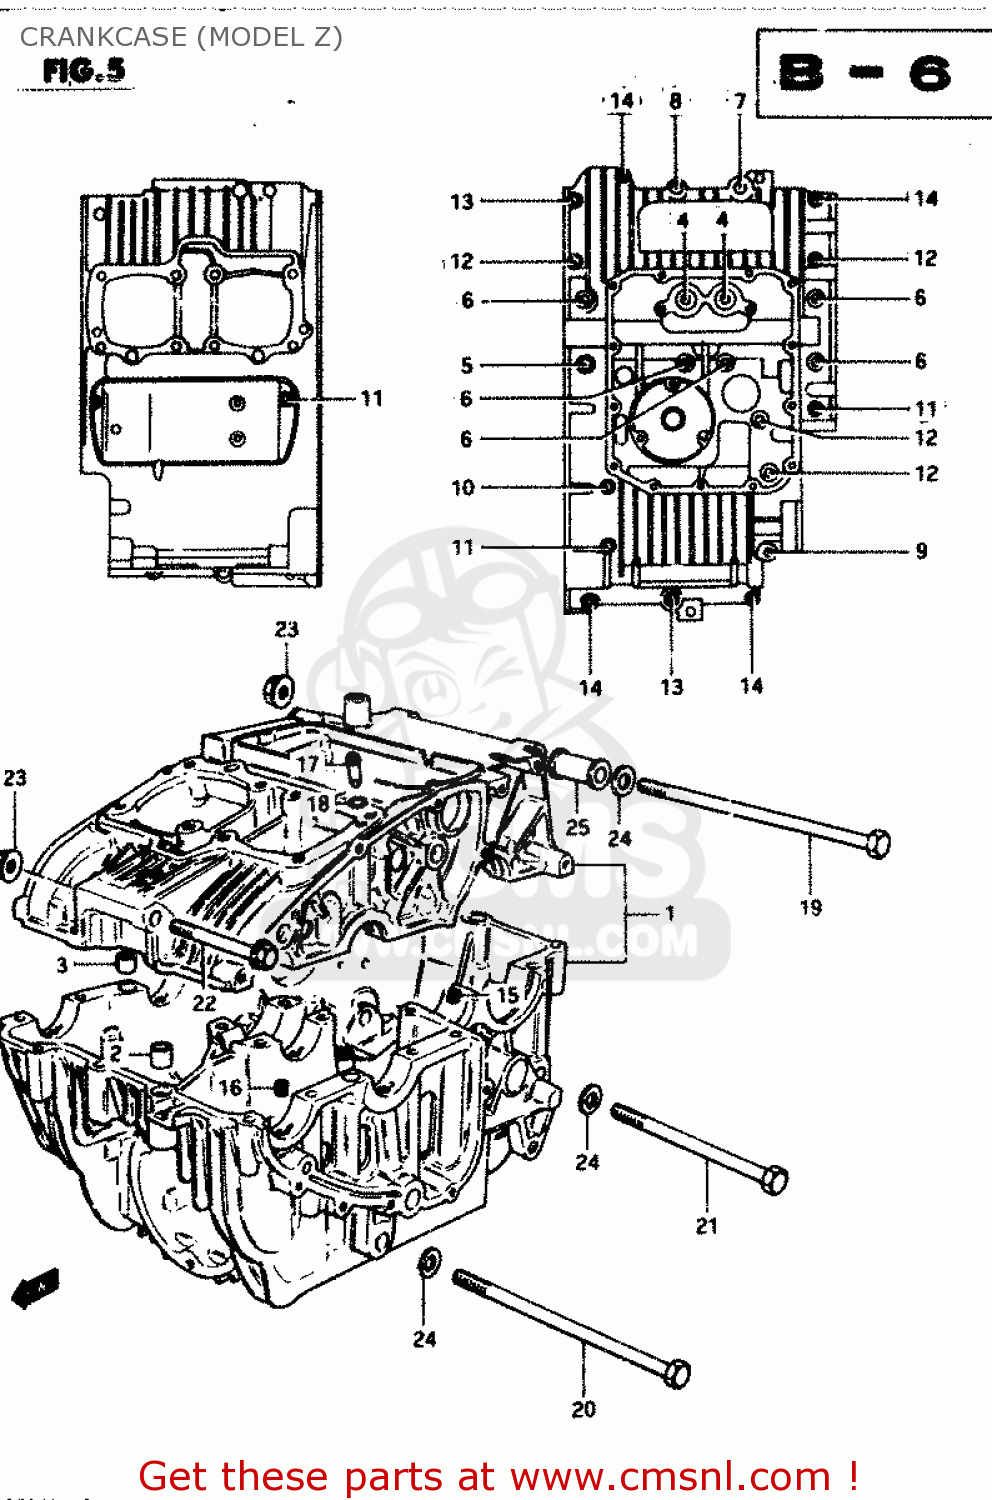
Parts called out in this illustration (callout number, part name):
1	CRANKCASE SET
2	PIN(10.4X13X22)
3	PIN (11X20)(SUS)
4	BOLT
5	BOLT
6	BOLT
7	BOLT 8X65
8	BOLT
9	BOLT (8X40)
10	BOLT
11	BOLT(6X105)
12	BOLT (6X90)
13	BOLT (6X60)
14	BOLT,UNDER
15	JET,AIR(100)
16	JET,AIR
17	JET,AIR
18	O RING(D:1.05,ID:3.1)
19	BOLT(10X210)
20	BOLT 10X215
21	BOLT 10X160
22	BOLT
23	NUT 10MM
24	WASHER
25	SPACER,ENGINE MOUNT
